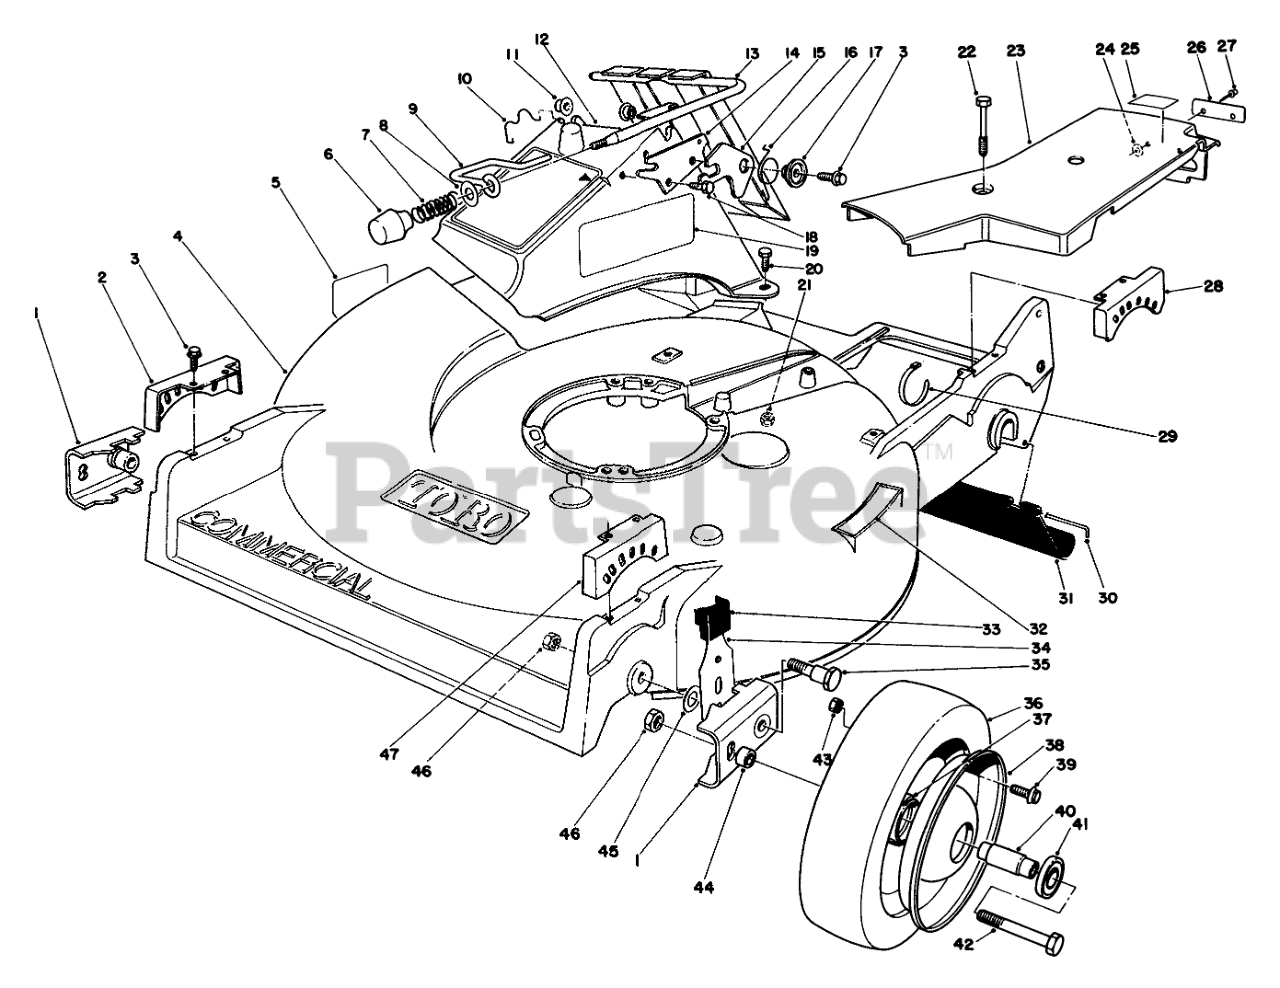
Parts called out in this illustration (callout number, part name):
1	PIVOT ARM
2	QUADRANT-FRONT, RH
3	Screw
4	Housing-Commercial (Incl. Ref. #5 & 32)
5	DECAL-DANGER
7	COMPRESSION SPRING
8	WASHER-FLAT
9	DOOR LATCH
10	DOOR RETAINER
11	BUSHING-NYLON
12	Chute & Door Assy. (Incl. Ref. #3, 6-11 & 13-21)
13	DOOR & HANDLE WA
14	DOOR LATCH PLATE
15	SAFETY LATCH
16	TORSION SPRING
17	DOOR SPACER
18	SCREW-HWH
19	DECAL SAF INST
20	SCREW-HH
21	NUT-LOCK, NI
22	SCREW-HHFTF
23	Belt Cover Asssmbly (Incl. Ref. #24, 26-27)
24	WASHER-PLAIN
25	LABEL-GREASE
26	NAMEPLATE-GRD SPEED
28	QUADRANT-REAR, LH
29	TIE-CABLE
30	ROD-SHIELD
31	SHIELD-TRAILING
32	STEP PAD DECAL
33	KNOB-ARM
34	SPRING ARM ASM-FRONT
35	PIVOT SCREW
37	HUB-BEARING
38	Wheel-Half
39	SCREW-HHF
40	SPACER-BEARING
41	BEARING-WHEEL
42	SCREW-HH
43	NUT-LOCK, NI
44	SPACER-WHEEL
45	WASHER-PIVOT
46	NUT-LOCK, NI
47	QUADRANT-FRONT, LH
